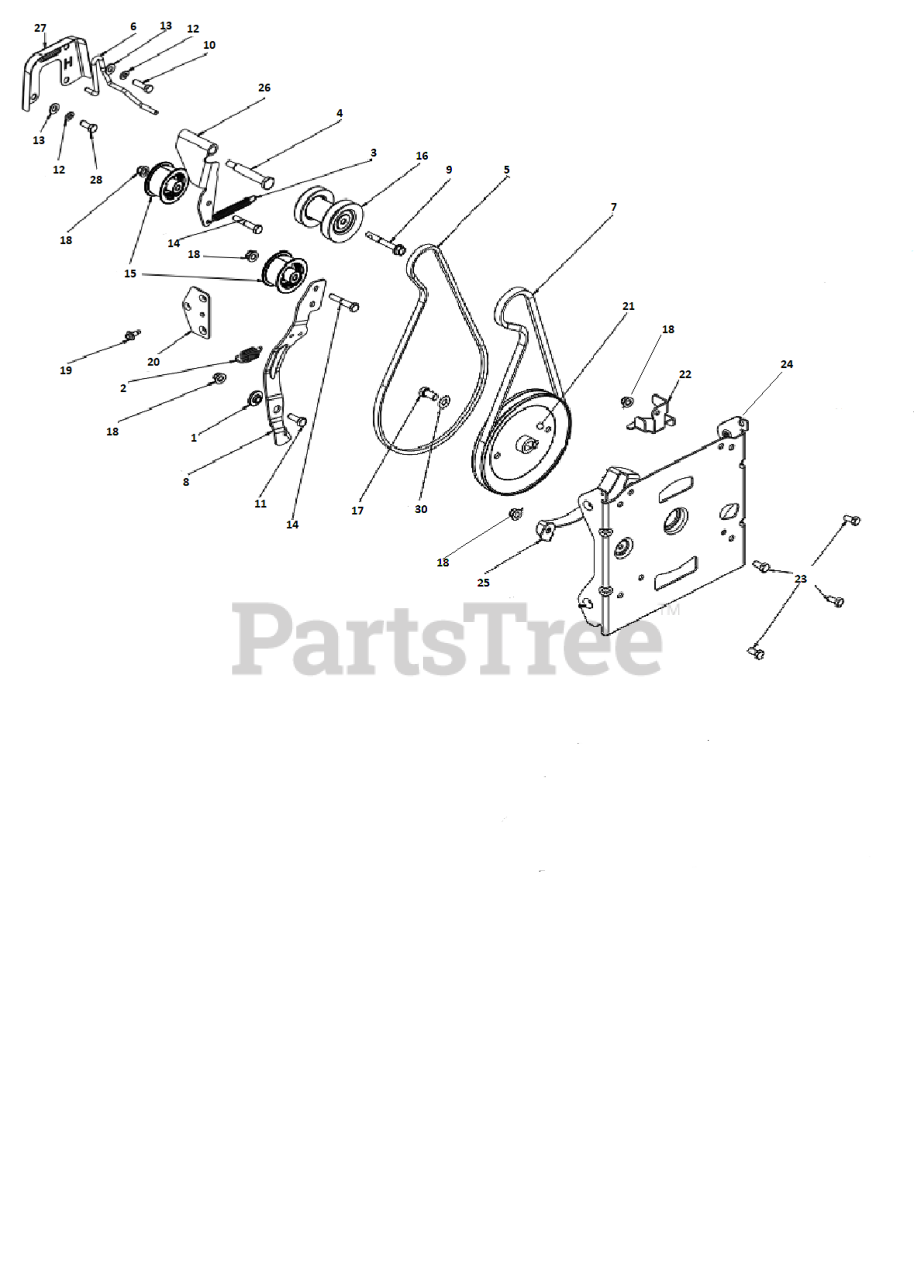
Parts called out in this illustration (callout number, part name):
1	BUSHING.BRAKE.ARM
2	SPRING RETURN, IDLER ARM, IMPE
3	SPRING RETURN IDLER ARM
4	BOLT 5/16-24X2.25 HEX HEAD SHO
5	BELT 3L 39.68; POLY CORD
6	Belt Keepers
7	HIGH CRANK IMPELLER BELT
8	ARM.IDLER.AUTO-PH.676
10	SCREW
11	BOLT HEXAGON BOLT 5/16-18 X 7/
12	WASHER SPRING LOCK WASHER WITH
13	WASHER 11/32 X 11/16 X 14 GA T
14	BOLT, HEX 5/16-18X1-3/4
15	PULLEYIDLER.2.0.W/SPACER.CZ
16	PULLEY 4L GEAR - HC
17	BOLT
17	SCREW HEXAGON HEAD FLANGE 3/8-
18	NUT HEXAGON FLANGE 5/16-18 ST
19	HEX.WASHER.HEAD 1/4-20 X .65
20	BRACKET NUT BLACK ZINC PLATE
21	PULLEYS
21	PULLEY IMPELLER DD 4L
22	GUIDE.LOWER.AUGER.BELT.479
24	BRACKET.AUG.HOUSING.INTER.BLAC
25	BRACKET.BELT.KEEPER.LOWER.BLAC
26	ARM DRIVE IDLER CLEAR ZINC PLA
28	SCREW 5/16-24 X .75 GR5
30	WASHER PLAIN WASHER 3/8 X 0.08
